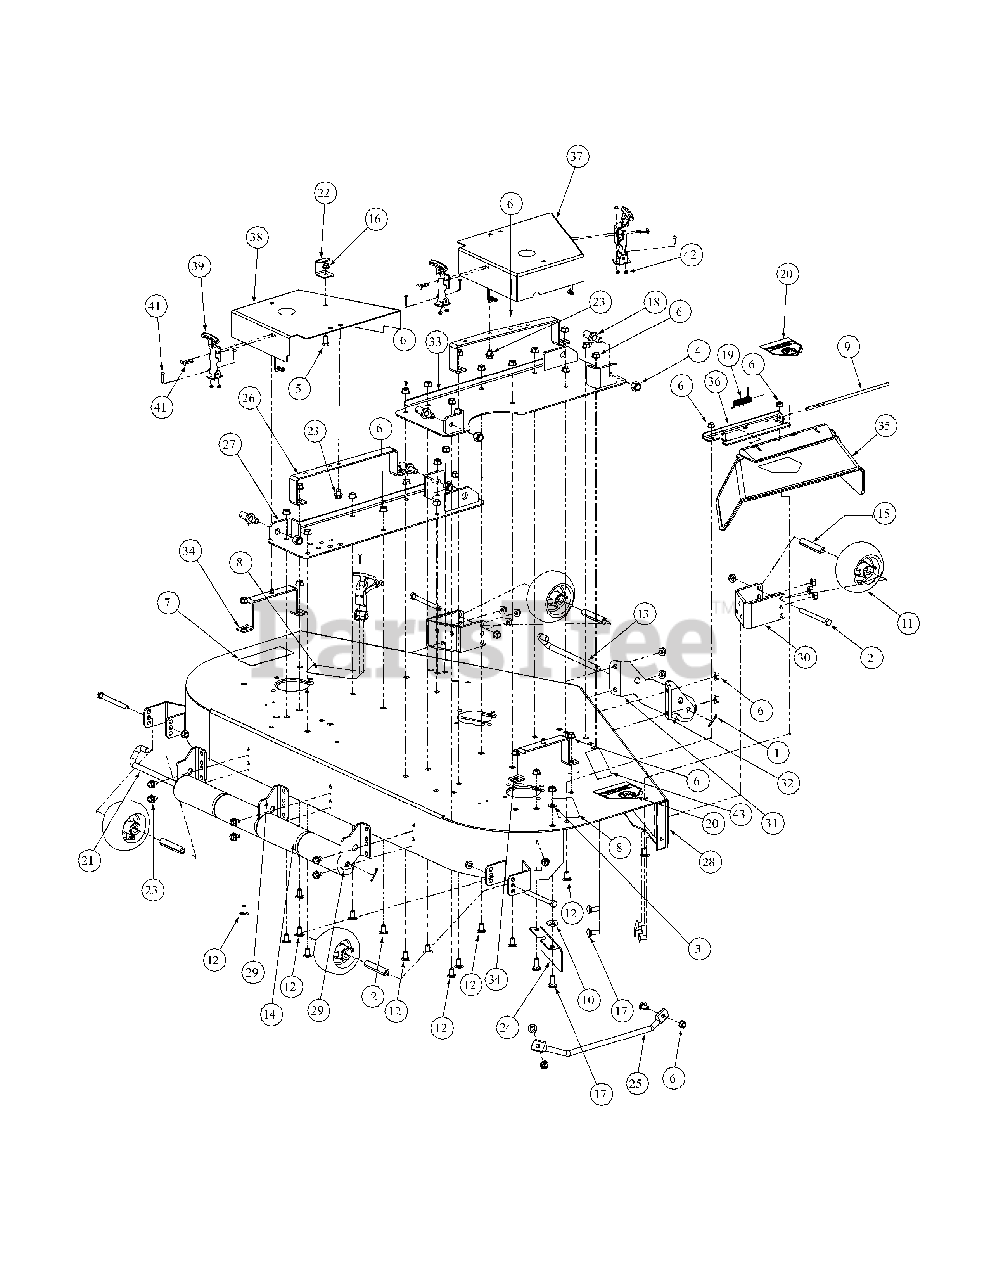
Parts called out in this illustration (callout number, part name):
1	Cotter Pin, .125 Dia x 1.0
2	Hex Cap Screw, 3/8-16, 3.75
3	Flat Washer, 3/8
4	Lock Nut, Nylon Insert, 1/2-13
5	Hex Cap Screw, 5/16-18 x 3/4
6	Hex Nut, 3/8-16 Flange Lock
7	Decal Rotating Blade
8	Decal, Warning Shield Missing
9	Defllector Chute Rod
10	Idler Washer
11	Complete Wheel, 5.00 Dia.
12	Carriage Bolt, 3/8-16 x .75 Lg.
13	Roller Pin. 1/2 Dia. x 7.31 Lg.
14	Front Roller
15	Wheel Spacer
16	Hexflange Lock Nut, 5/16-18
17	Carriage Bolt, 3/8-16 x 1
18	Pin, 5/8 Dia. x 1.2 Lg.
19	Spring Torsion, 0.4 ID x 2.16 LG
20	Decal, Danger Hands and Feet
21	Roller Pin
22	Tension Rod Stop Bracket
23	Hex Index Washer Screw, 3/8-16, .5
24	Chute Bracket
25	Finger Guard
26	Cover Support
27	Left Hand Mount, Deck Bracket Assembly
28	54 Deck Assembly
29	Roller Mount Bracket
30	Anti-Scalp Wheel, Front Mount Bracket
33	Deck Bracket Assembly
34	Outer Belt Cover Support Assembly
35	Deflector Chute
36	Deflector Chute Bracket
37	Right Hand Belt Deck Cover Weldment
38	Left Hand Belt Deck Cover Weldment
39	T-Handle Draw Latch
41	Phillips Head Screw, 10-32
42	Lock Nut, Nylon Insert, 10-32
43	Mower Deck Label
